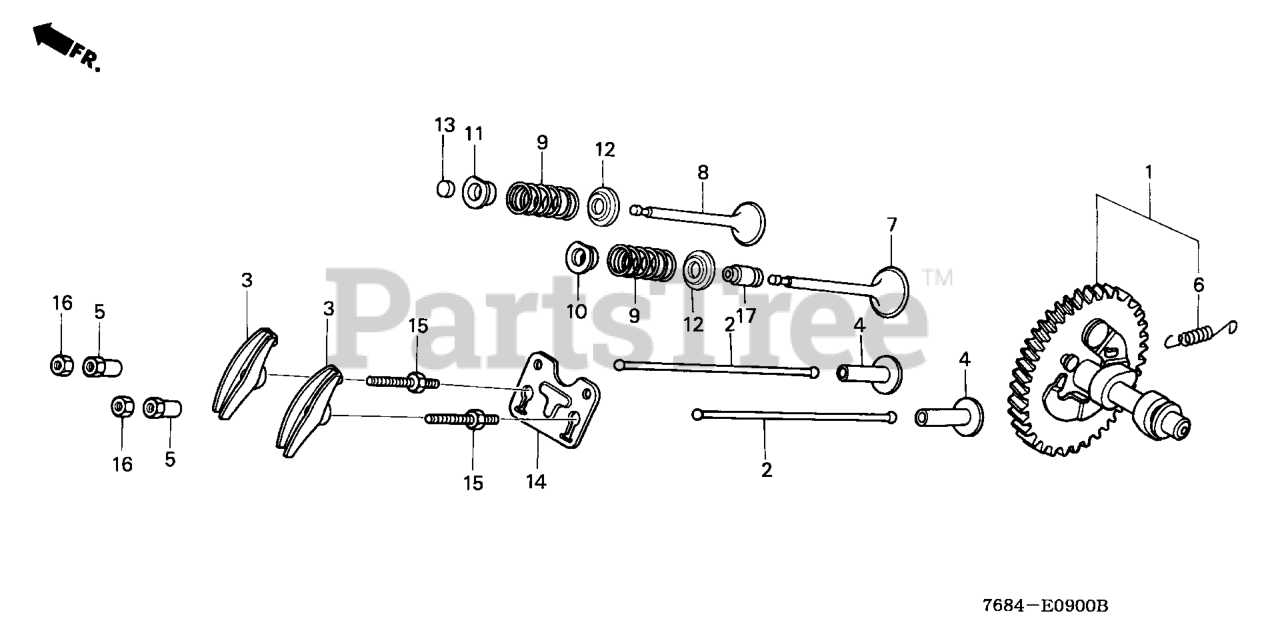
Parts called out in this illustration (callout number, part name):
1	CAMSHAFT ASSY.
2	ROD, PUSH
3	ARM, VALVE ROCKER
4	LIFTER, VALVE
5	PIVOT, ROCKER ARM
6	SPRING, WEIGHT RETURN
7	VALVE, IN.
8	VALVE, EX.
9	SPRING, VALVE
10	RETAINER, IN. VALVE SPRING (EXHAUST SIDE)
11	RETAINER, EX. VALVE SPRING
12	SEAT, VALVE SPRING
13	ROTATOR, VALVE
14	PLATE, PUSH ROD GUIDE
15	BOLT, PIVOT (8MM)
16	NUT, PIVOT ADJ.
